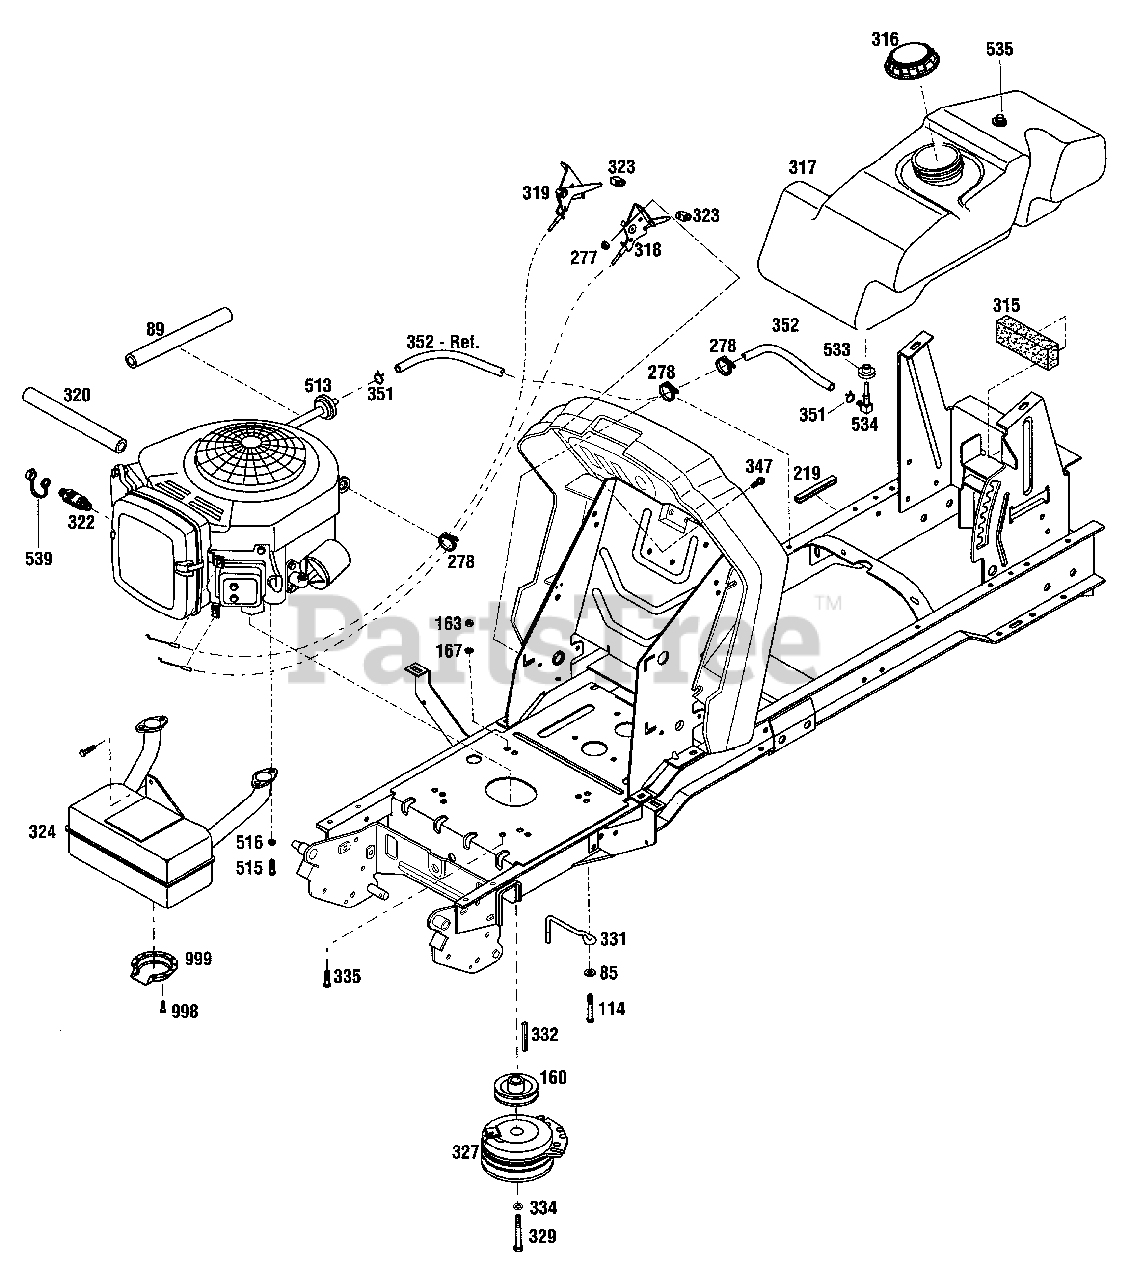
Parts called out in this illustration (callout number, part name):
85	Flat Washer, 318
89	Fuel Line Insulation
114	Thread-Forming Screw, 318 x 1-1/2
160	Engine Sheave
163	Hex Nut, 3/8-16
167	Lockwasher, 3/8
277	Keps Locknut,10-24
278	Cable Tie
315	Fuel Tank Pad
316	Fuel Cap
317	Fuel Tank
318	Throttle Control
319	Choke Control
320	Oil Drain Hose
322	Oil Valve Assembly
323	Control Knob
324	Muffler (Twin Inlet)
327	Electric Clutch
329	Hex Head Screw, 7/16-20 x 3-1/4
331	Clutch Retainer
332	Square Key, 1/4 x 1-1/2
334	Spring Lock Washer, 7/18
335	Hex Head Screw, 3/8-18 x 1
347	Machine Screw, 10-24 x 3/4
351	Hose Clamp
352	Fuel Line
513	Fuel Filter
515	Hex Head Screw, 1/4-20 x 1
516	Lockwasher, 1/4
533	Bushing
534	Fuel Tank Show
535	Fuel Tank Vent
539	Oil Drain Cap
998	Self Tapping Screw, #8-32 x 3/8
999	Muffler Deflector
